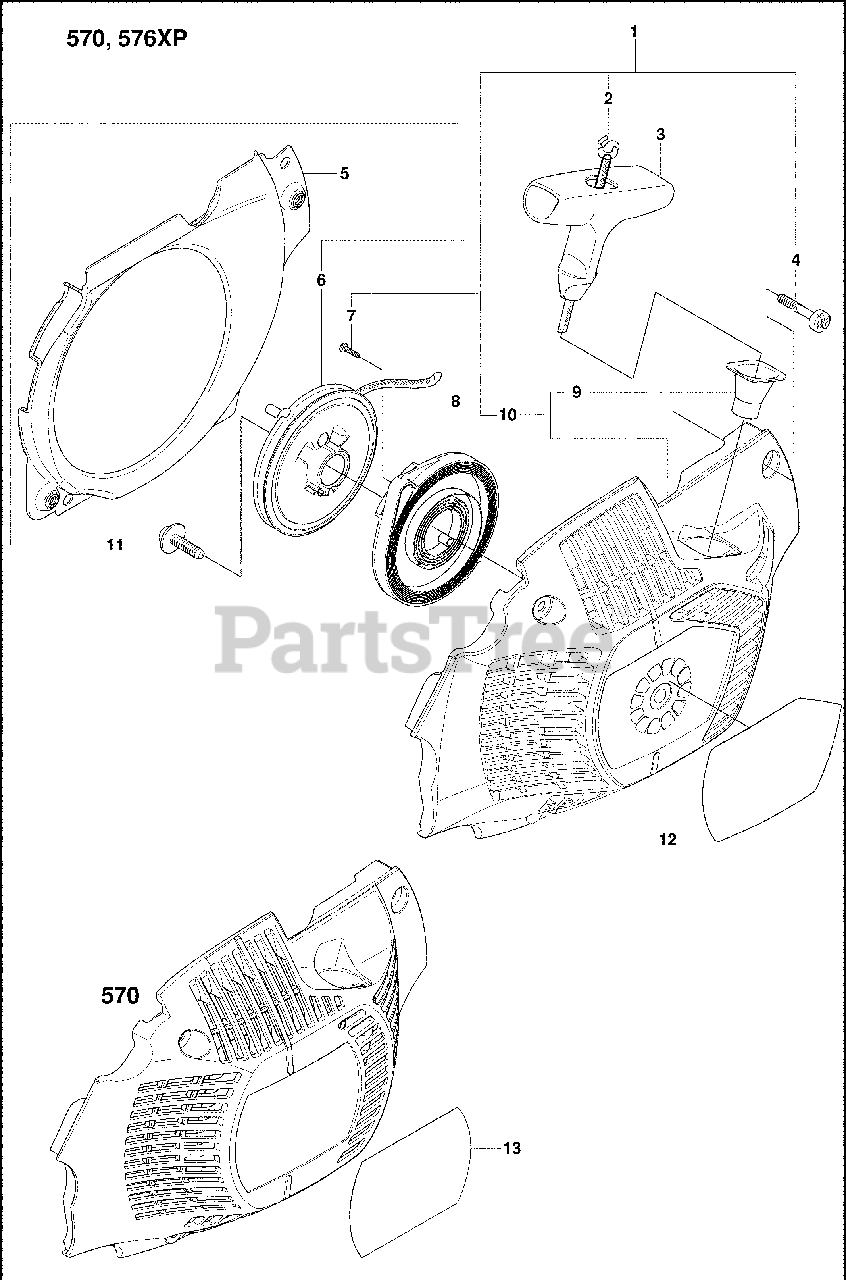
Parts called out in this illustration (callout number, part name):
1	Starter Assembly
1	Starter Assembly, Complete
2	Starter Rope
4	Screw, Citxpanmo
6	Starter Pulley
8	Spring
10	Starter Housing
10	Starter Cover
12	Label
13	Decal
